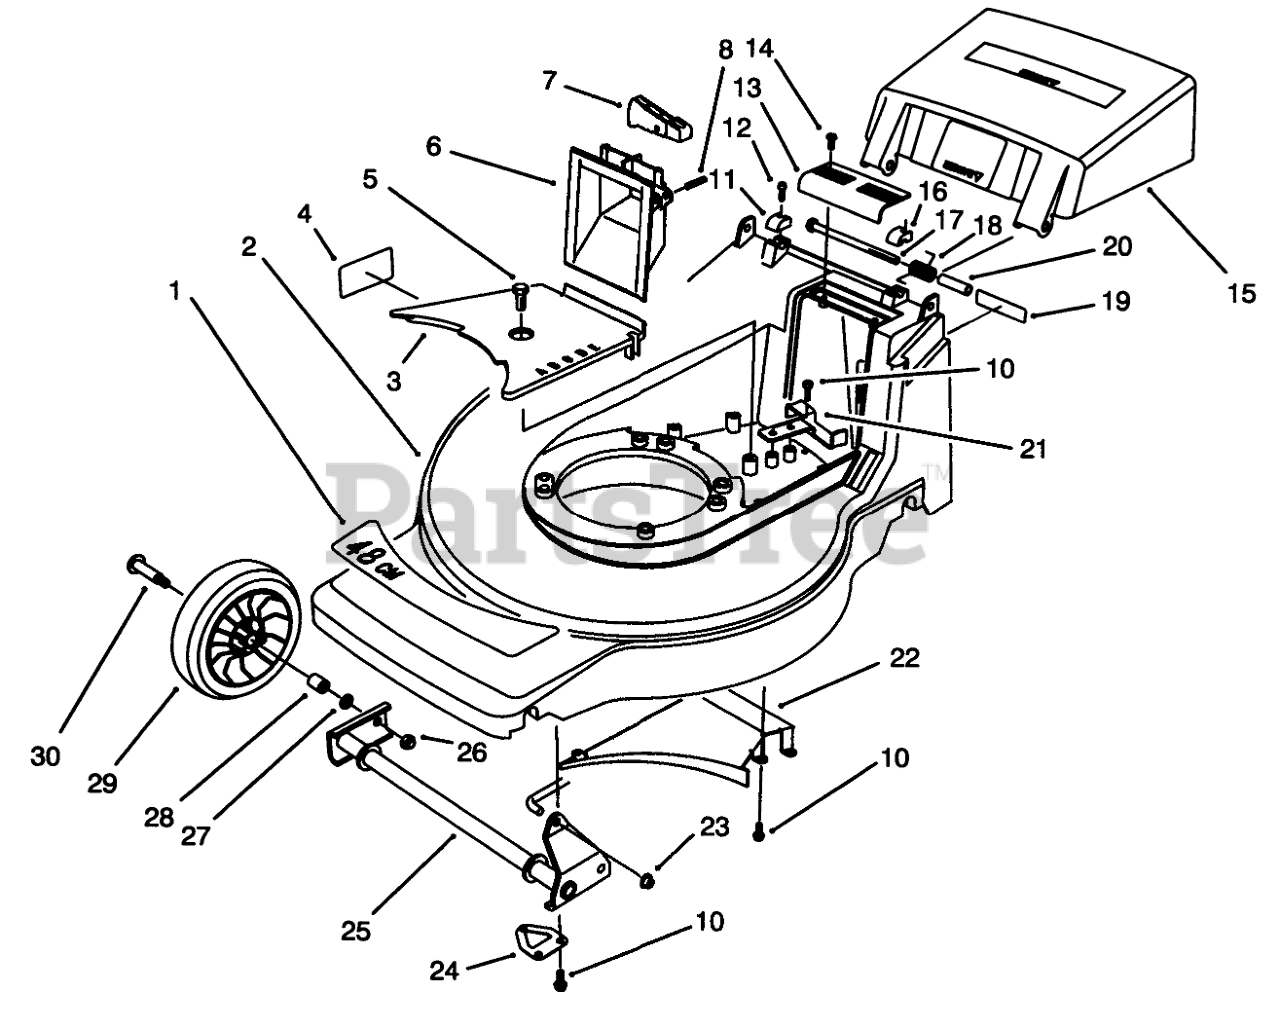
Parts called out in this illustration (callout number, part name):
1	DECAL - DECK 48 CM
2	Housing-48cm (Incl. Ref. #4)
3	BELT COVER
4	DECAL - DIN/DANGER
5	SCREW-HWHTF
6	GRIP - LOWER
7	TRIGGER - HOC
8	PIN-SPIRAL
10	SCREW-HWH
11	CAP-HINGE BOLT, RH
12	SCREW-HSH
13	GRIP-UPPER
14	SCREW-PPH, PLASTITE
15	Door Discharge
16	CAP-HINGE BOLT, LH
17	SCREW-HH
18	SPRING-DOOR
19	DECAL FRENCH REGUL.
20	SPACER-DOOR
21	REAR BELT GUIDE
22	Ramp-Discharge
23	NUT-PUSH
24	SHAFT RETAINER ASM
25	FRONT PIVOT WA
26	NUT-HEX
27	WASHER
28	BUSHING
29	Wheel & Tire Assembly (Incl. Ref. #28)
30	BOLT-WHEEL
